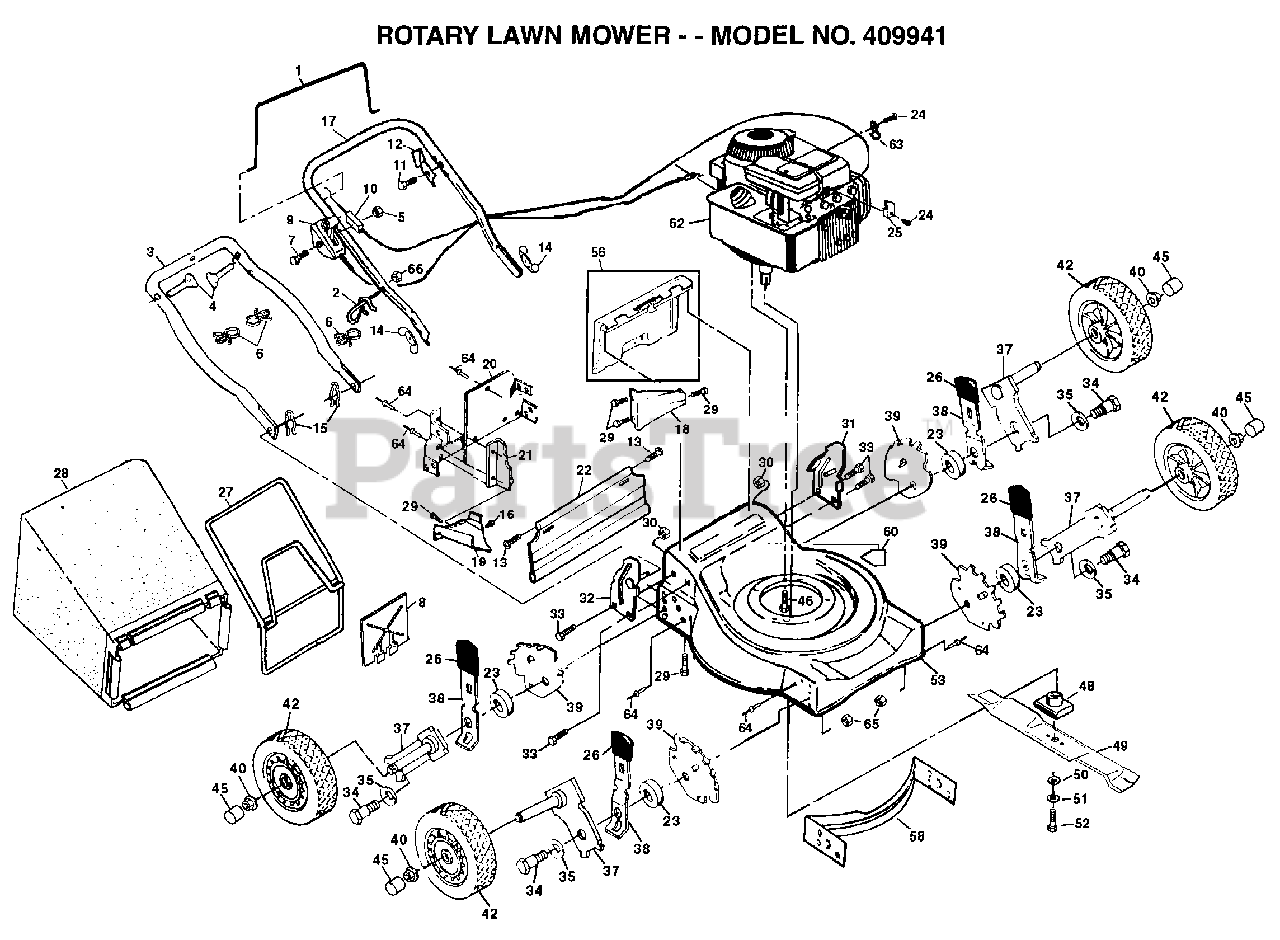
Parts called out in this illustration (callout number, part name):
1	CONTROL BAR PM
2	ROPE GUIDE
4	BOLT.HANDLE.LM
7	SCREW.HXHD.WASH.
8	MULCHER PLATE
9	CONTROL THROTTLE
10	"CABLE,ENG ZONE CO"
11	TAPPING SCREW
12	"BRKT,UPSTOP"
13	HINGE SCREW
14	"NUT,WING PM"
15	HAIRPIN COTTER
16	SCREW.HXTAP.10-24
18	REAR BAFFLE
19	DISCHARGE GUARD
20	PLATE.BACK.20RD
22	SKIRT.PUSH.20RD
23	SPACER.HEIGHT.ADJ
24	SCREW PM
25	CABLE CLAMP
26	KNOB PM
27	FRAME.CATCHER.2.5
28	GRASSBAG.250B1.BL
29	SCREW
31	BRACKET.HDL.LH.
32	BRACKET.HDL.RH.
33	SCREW.HXWS.5/16
34	BOLT.SHLD.W/PATCH
35	"WASHER, BELLEVIL."
37	ARM.AXLE.ASM.BZP.
38	SPRING SELECTOR
39	BRACKET.ADJ.9POS.
40	HEX FLANGE LOCKNT
42	WHEEL.ASM
45	HUB CAP-PLASTIC
46	BOLT.ENG.3/8-16
48	BLADE ADAPTOR
49	BLADE.20.MULCH.AY
50	"WASHER,HARDEN"
51	LOCKWASHER
52	SCREW
53	HOUSING ASSY
56	KIT.DOOR.RR.20STL
60	DECAL DANGER E/S
63	GUIDE CLIP PM
64	BLIND RIVET
66	NUT
